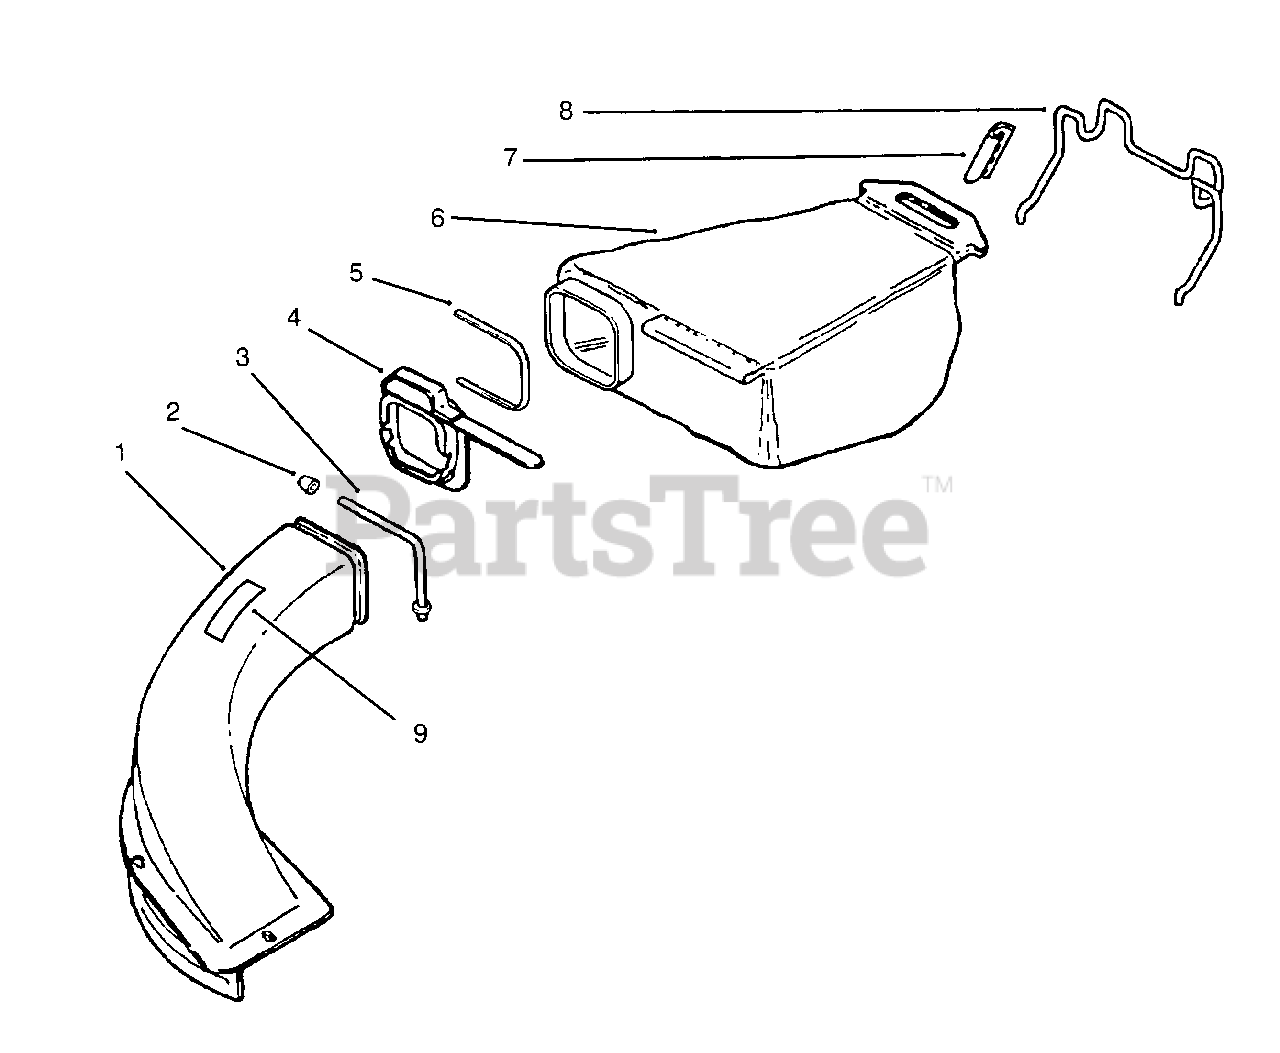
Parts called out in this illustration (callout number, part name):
1	Chute & Support Assembly (Incl. Ref.# 2,3 & 9)
2	Nut-Cap
3	Chute Support
4	Adaptor Assembly
5	Tie Strap
6	Bag Assembly
7	Hanger Clamp
8	Wide Hanger
9	Decal-Danger
